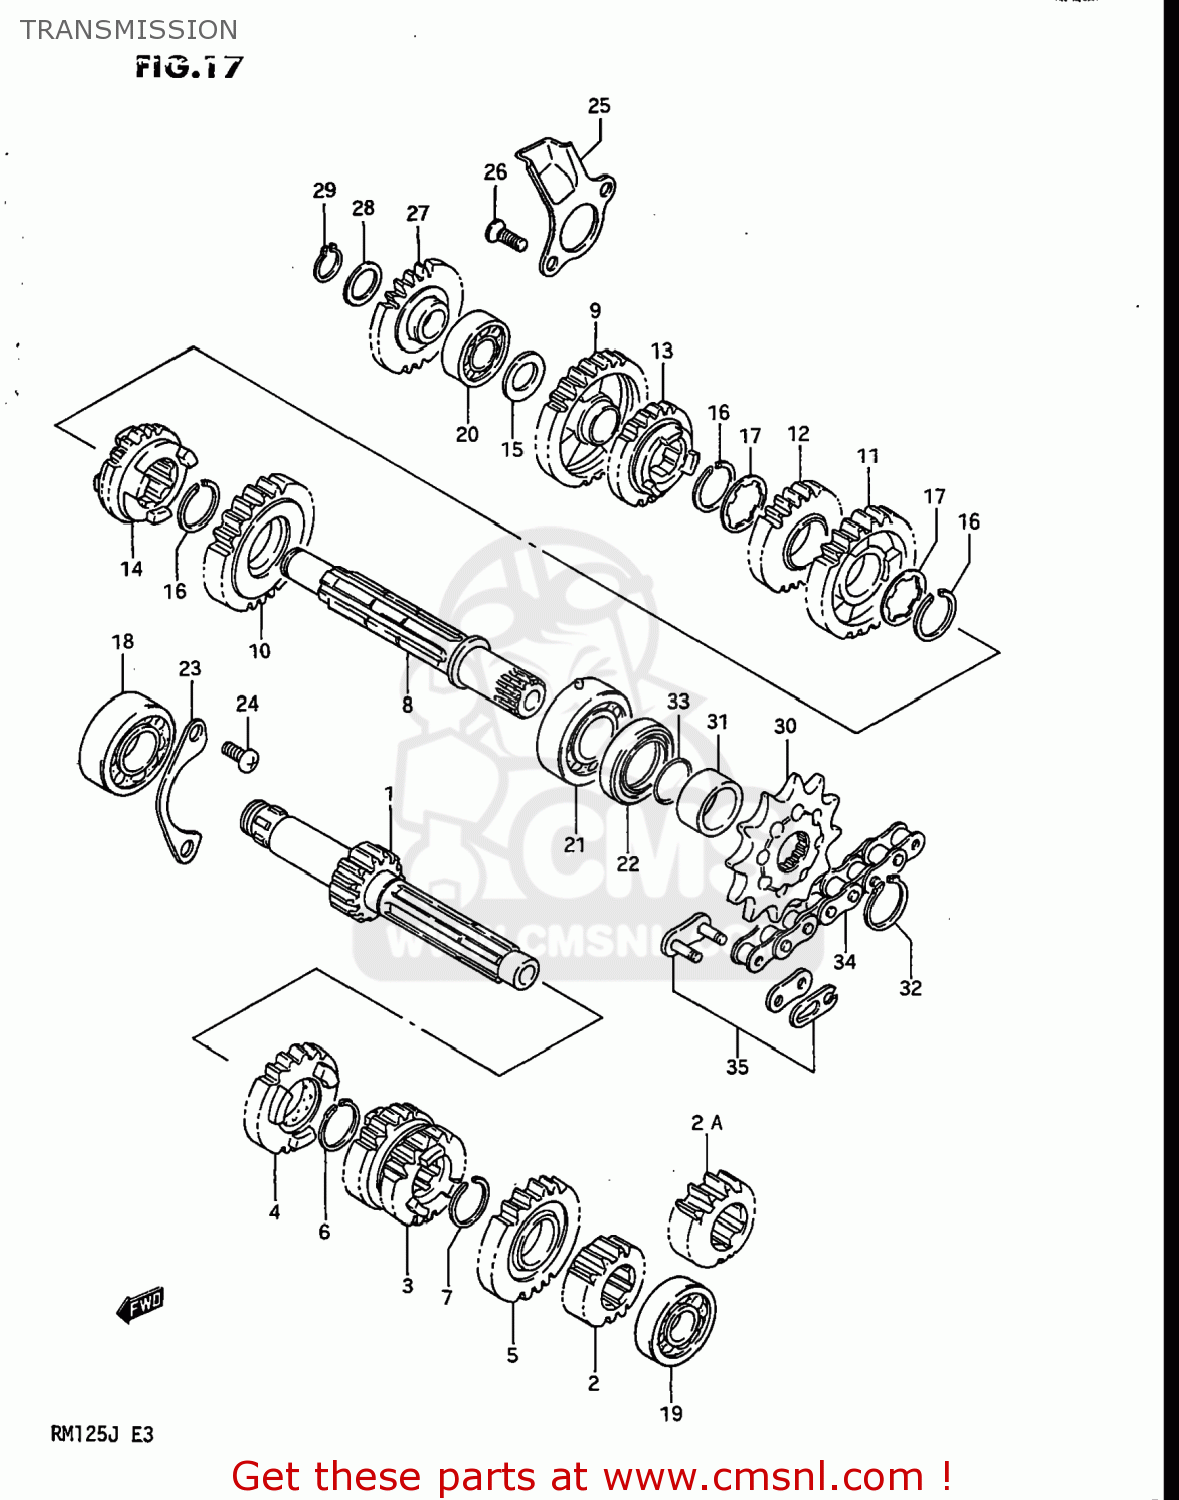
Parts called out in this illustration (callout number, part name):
1	SHAFT,COUNTER
2	GEAR,SECOND DRIVE (NT:13)
2A	GEAR,SECOND DRIVE
3	GEAR,THIRD & FOURTH DRIVE
4	GEAR,FIFTH DRIVE (NT:19)
5	GEAR,SIXTH DRIVE (NT:20)
6	CIRCLIP
7	CIRCLIP
8	SHAFT,DRIVE
9	GEAR,FIRST DRIVEN
10	GEAR,SECOND DRIVEN
11	GEAR,THIRD DRIVEN
12	GEAR,FOURTH DRIVEN
13	GEAR,FIFTH DRIVEN
14	GEAR,SIXTH DRIVEN
15	WASHER,THRUST
16	CIRCLIP
17	WASHER,LOCK
18	BEARING
19	BEARING
20	BEARING
21	BEARING(20X47X14)
22	SEAL,OIL(25X40X7)
23	RETAINER,CENTER SHAFT BEARING
24	SCREW 6X12
25	PLATE,DRIVESHAFT BEARING
26	SCREW
27	GEAR,KICK STARTER IDLE
28	WASHER,THRUST
29	CIRCLIP,15MM
30	SPROCKET,ENGINE
31	SPACER(20X25X12.8)
32	CIRCLIP
33	O RING(D:1,ID:19.5)
34	CHAIN ASSEMBLY,DRIVE
35	JOINT ASSEMBLY,CHAIN
